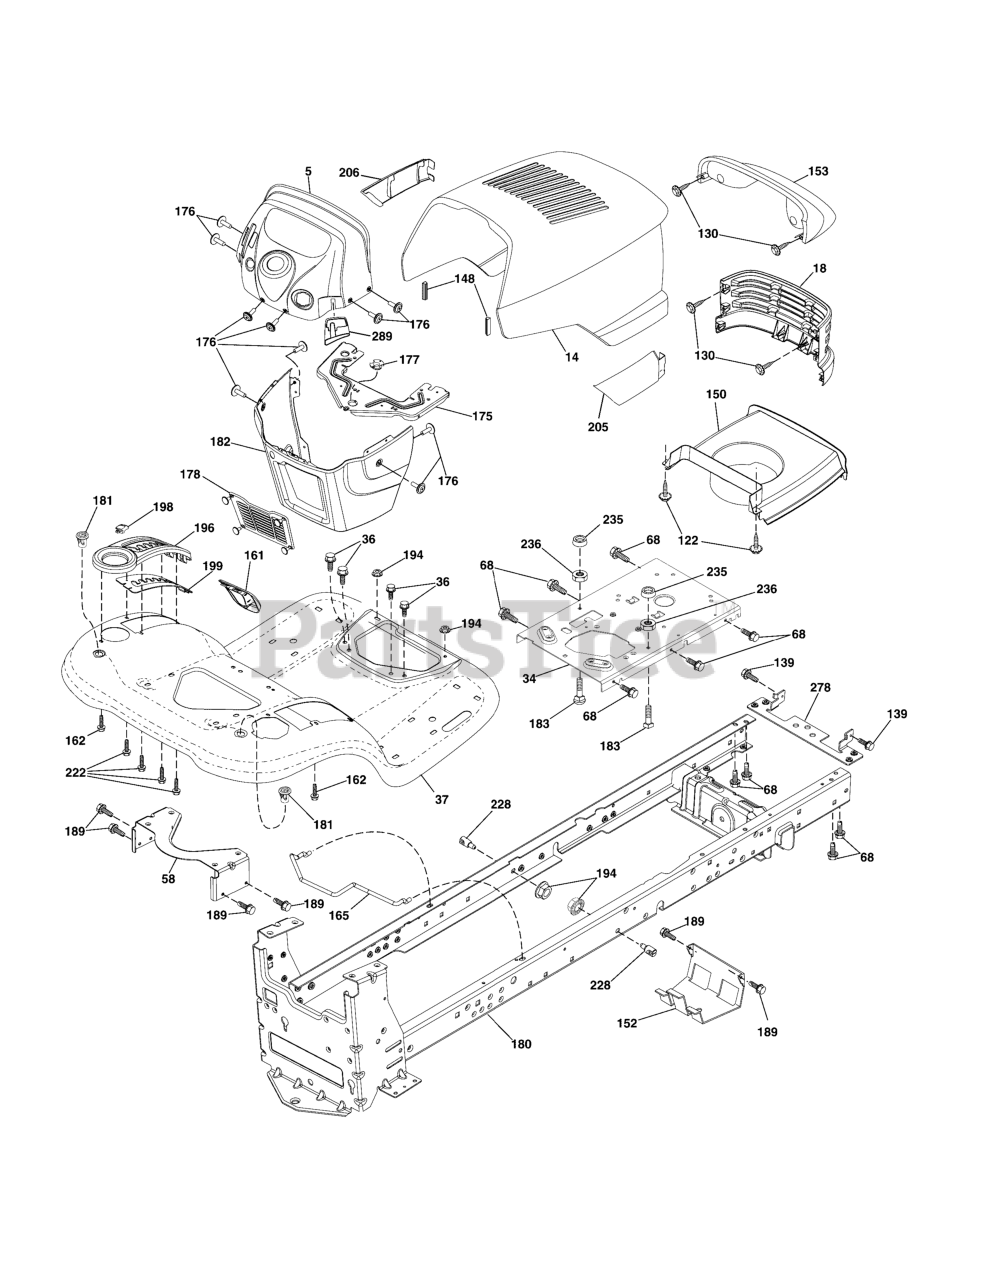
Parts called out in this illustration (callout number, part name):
18	Grille
34	Plate Engine
36	Screw 5/16-18 x 3/4
37	Fender
58	Bracket Fender
68	Screw Thdrol 5/16-18 x 1/2
122	Screw WSHD Hex 10-32 x 5/8
130	Screw 10 x .750 BOS Thread
139	Bolt Shoulder
148	Bumper
150	Duct Heat Hood
152	Shield Browning/Debris
153	Lens Bar
161	Console Fuel Window
162	Screw Hex Wsh Hi-Lo 1/4 x 1/2
165	Bracket Support Tank
175	Crossmember
176	Screw #10-24 x 5/8 Rnd Qudrx
177	Bushing Steering
178	Cargo Asm. Net
180	Chassis
181	Bushing Mtg. Fender Crgo.
182	Dash Lower
183	Bolt Fin Hex 5/16-18 unc x 1-1/4
189	Screw 5/16-18 x 3/4
194	Nut Lock Hex Flange 5/16-18
196	Console Asm. Deck Lift
198	Indicator Deck Lift
199	Plate Deck Lift
205	Skirt Hood RH
206	Skirt Hood LH
222	Screw Thd Roll 1/4-20 x 5/8
228	Stud Fastener
235	Spacer Fender
236	Nut Center Lock 5/16-18 unc
278	Bracket Pickoff Hood
289	Phone Plug
